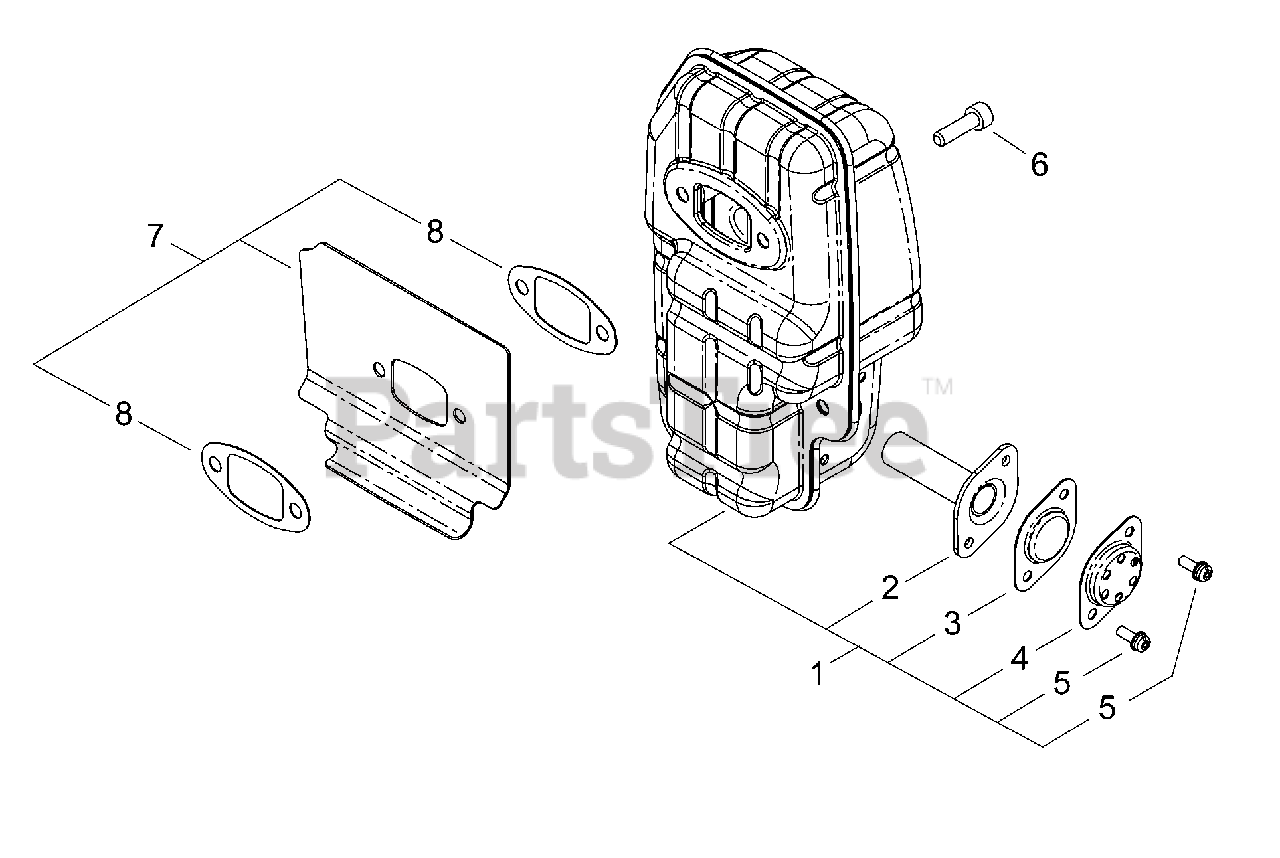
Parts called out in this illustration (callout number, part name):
1	MUFFLER ASSY
2	PIPE, EXHAUST
3	SCREEN, SPARK ARRESTER
4	GUIDE, EXHAUST
5	SCREW M4×12
6	BOLT 6×20
7	SHIELD ASSY, EXHAUST HEAT
8	GASKET, EXHAUST
